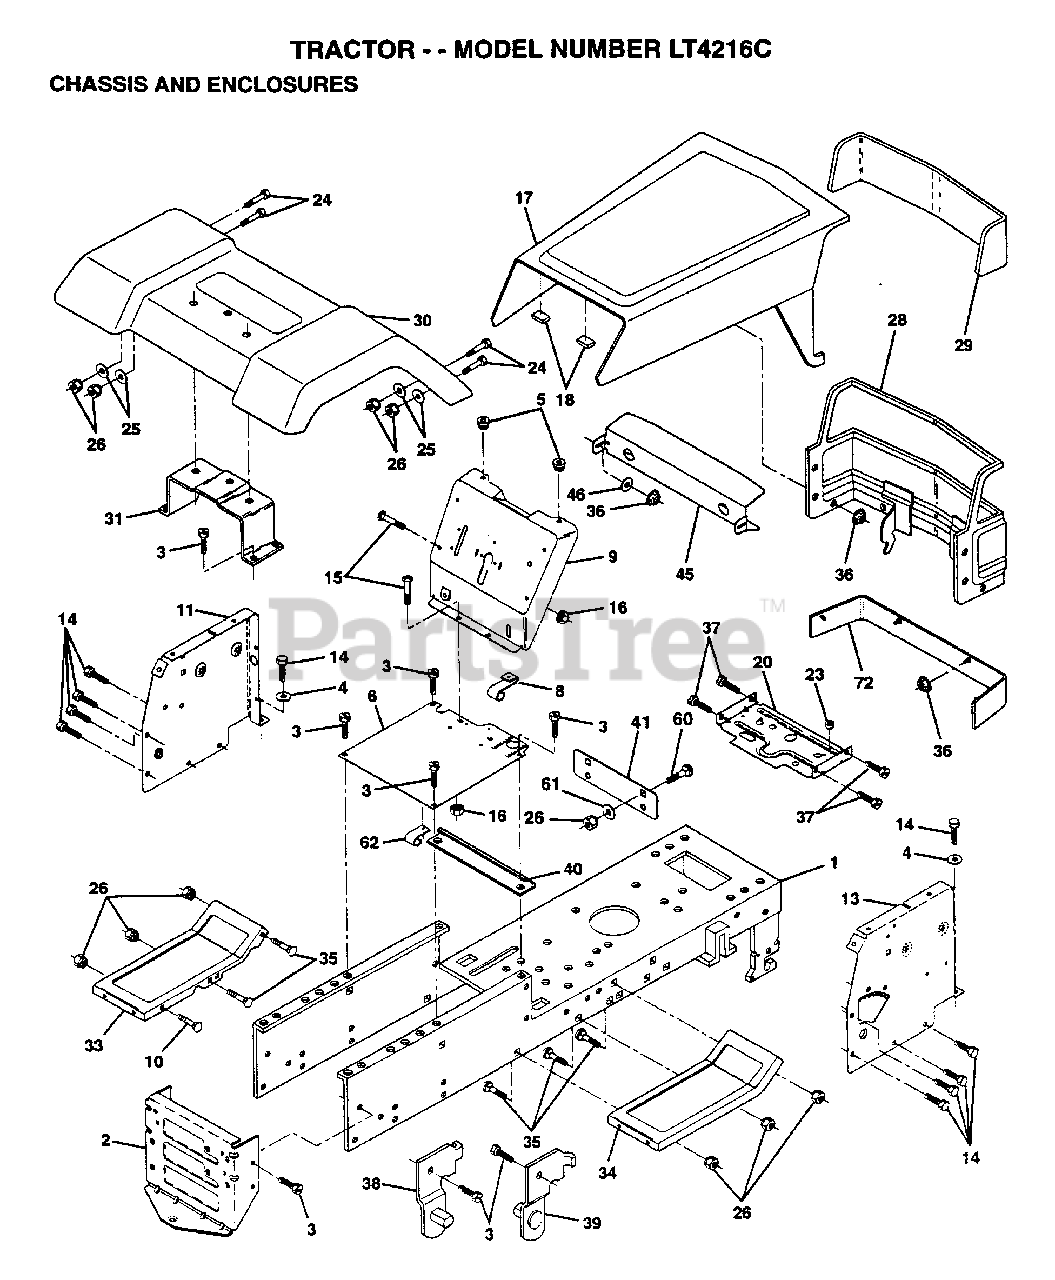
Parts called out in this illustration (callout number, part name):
1	CHASSIS.WLD.11GA
3	SCREW
4	WASHER
8	"CLIP,INSULATOR"
9	DASH.SLKSC.LT.1PC
11	DASH PANEL LH
14	SCREW LT
15	SCREW
17	HOOD/SD.PNLS.KGRO
20	PLATE.MTG.BTRY.TK
24	BOLT
25	WASHER
26	NUT
28	GRILLE.RALLY.BAR.
31	BRACKET SUPT FEND
33	FOOTREST.LH.LT/GT
34	FOOTREST.RH.LT/GT
35	BOLT
36	PAL NUT LT
37	SCREW LT
38	BRACKET ASM LH
39	BRACKET ASM RH
40	SPACER FENDER LT
41	PLATE EXTEN FEND
46	RETAINER
60	BOLT
61	WASHER
72	STRAP.GRILLE.PNT.
